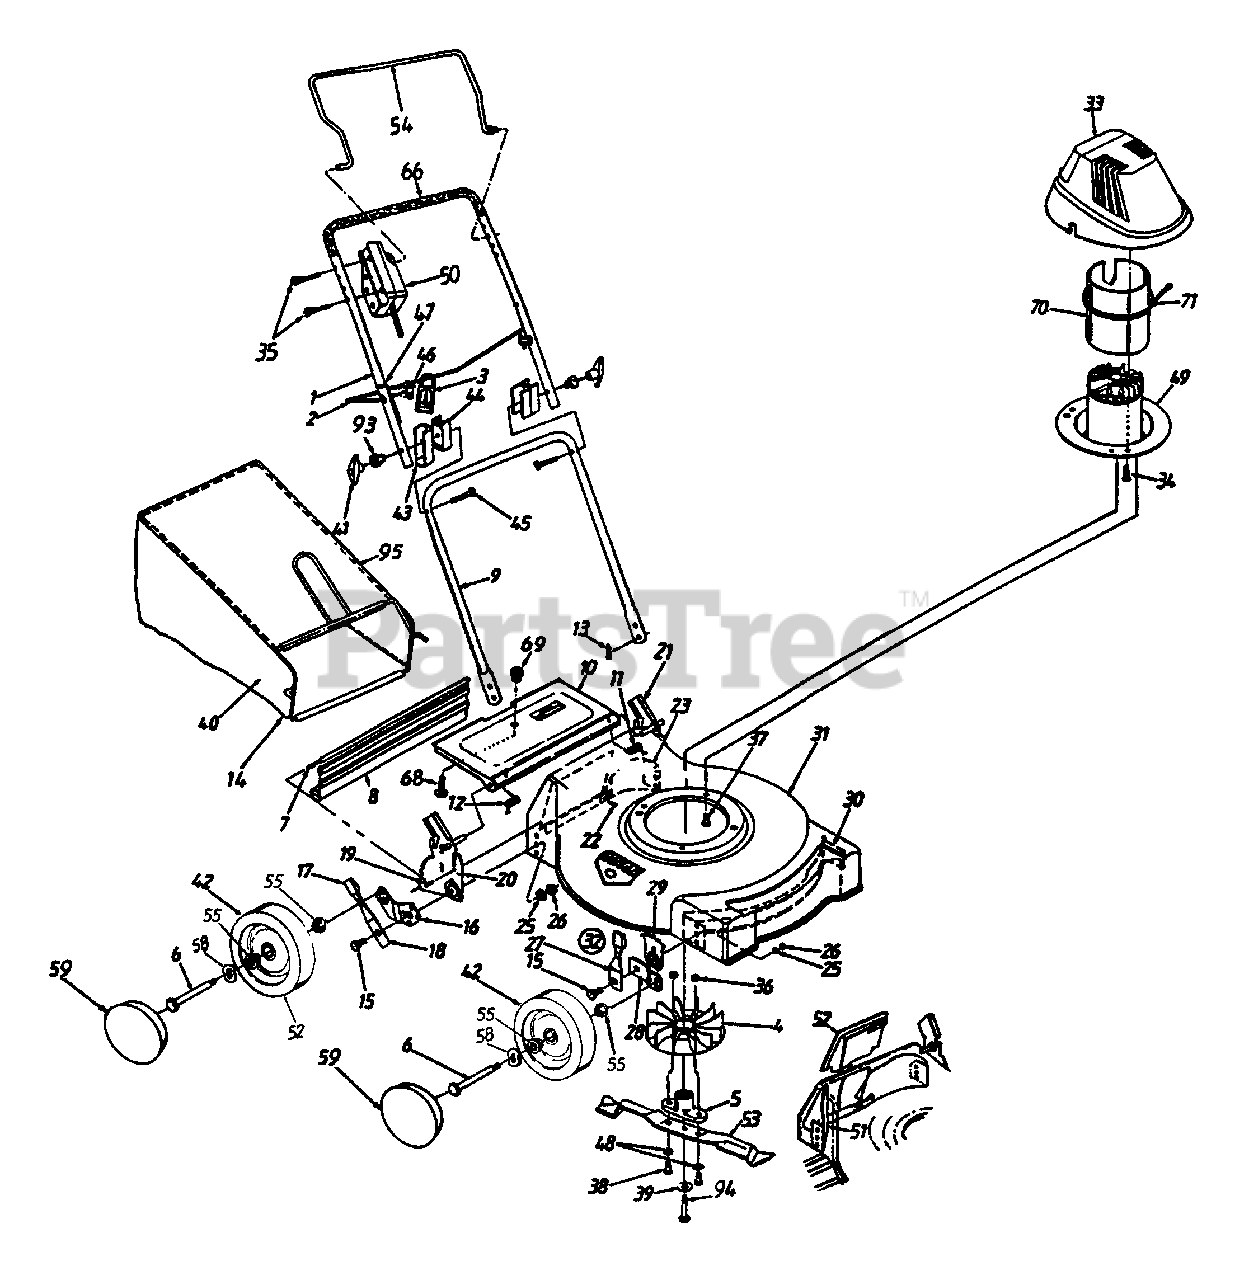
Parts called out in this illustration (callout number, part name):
3	Strain Relief - Cord
5	Blade Adapter
6	Axle Bolt
7	Rear Flap Wire
8	Rear Flap
12	Door Spring - R.H.
13	Hairpin Clip
16	Pivot Bar - R.H.
17	Spring Lever Knob
18	Spring Lever
19	Hex AB-Tap Scr. 1/4-14 x .62" Lg.
20	Handle Brkt. Ass'y.- R.H.
21	Handle Brkt. Ass'y.- L.H.
22	Torx. Mach. AB-Tap Scr. 1/4 x .62" Lg.
23	Rear Baffle
25	Bell-Wash..39" I.D. x 1.38" O.D.
26	Hex Nut 3/8-16 Thd.
27	Spring Lever Ass'y. w/Knob
29	Height Adj. Plate
34	Scr. #10-24 x 75" Lg
35	C-Sunk Scr. 1/4-20 x 1 8" Lg.
36	Hex Nut 3/8-24 Thd.
37	Hex TT-Tap Scr. 3/8-16 x 1" Lg.
38	Hex Bolt 3/8-24 x 1.25" Lg.
39	Bell-Wash .396" I.D. x 1.14"
40	Grass Bag
41	Plastic Knob
42	Wheel Ass'y. Comp.
43	Upper Handle Insulator
44	Lower Handle Insulator
45	Carriage Bolt 5/16-18 x 3" Lg.
47	Cable Tie
48	Bell-Wash. 3/8" I.D.
49	Motor, Cord & Switch Ass'y.
50	Cord & Switch Ass'y. Comp.
53	19" Mulching Blade
54	Control Handle
55	Ball Bearing
58	Wave Washer
59	Hub Cap
66	Foam Grip
68	Truss Scr. #10-24 x .38" Lg.
70	Brush and Liner Ass'y.
71	Brush Holder Cap
93	Insulator - Knob
94	Hex Bolt 3/8-24 x 2 5"
